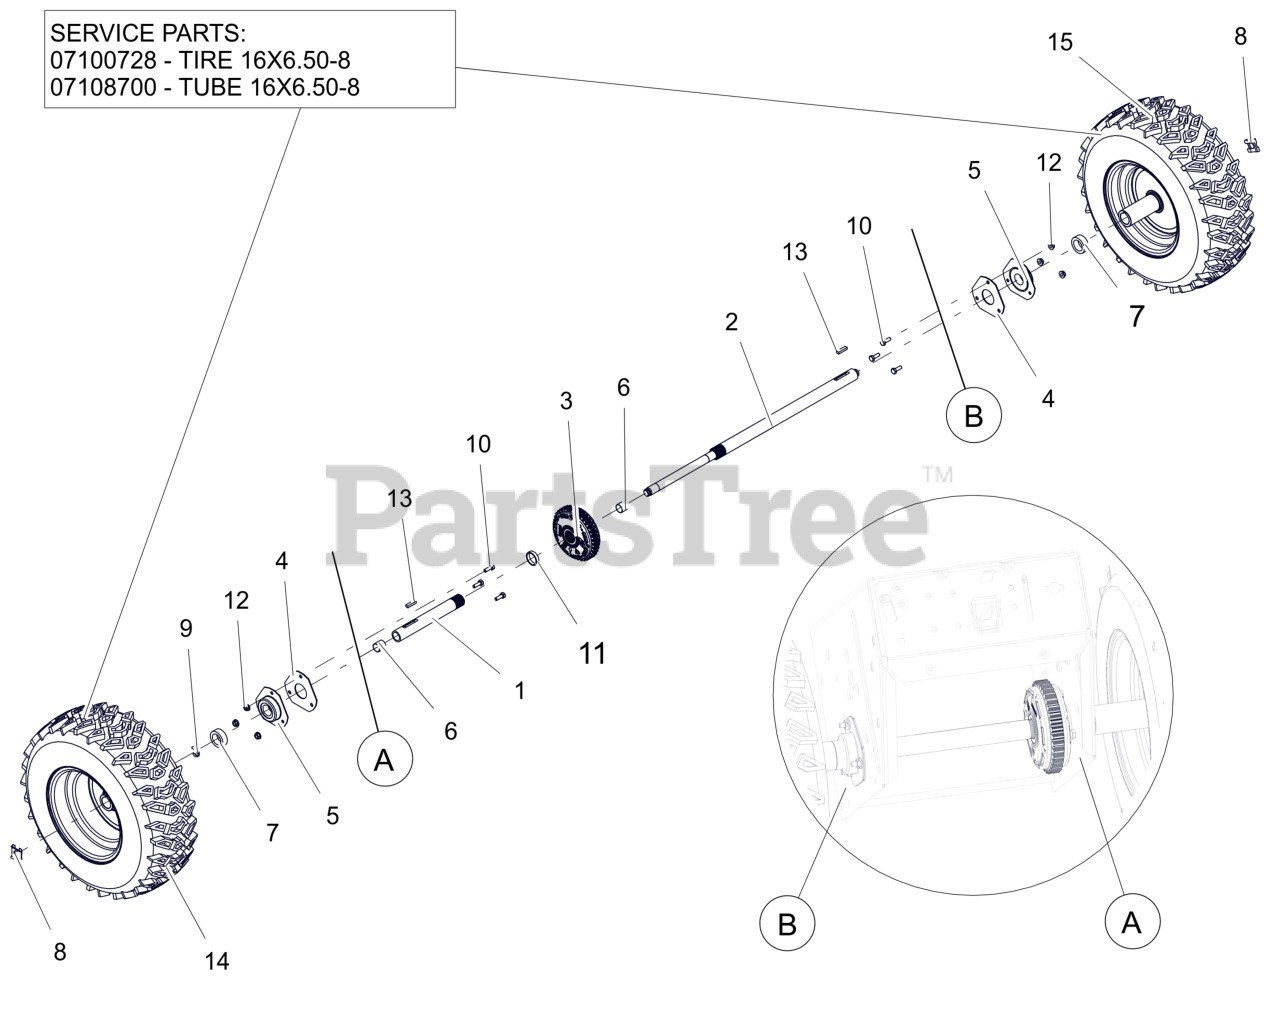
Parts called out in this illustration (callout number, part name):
1	AXLE, SHORT-AUTO W/BUSHINGS
2	AXLE, LONG-PRO AUTO DIFF
3	DIFFERENTIAL, AUTOMATIC
4	PLATE, BEARING SPACER
5	BRG-FLG 1.003/1.000 3 BOLT
6	BSHG-SLV .706X.764X.75 BRZ
7	SPACER, PRO AXLE BEARING
8	CLIP, SNAP .625 DIA
9	RG-RTNG-EXT .625X.042
10	BLT, HEX .25-20X.75 G5 ZCC
11	BSHG, SLV 1.062X1.228X.268
12	NUT-LK-CTR-FLG .25-20 ZC120
13	KEY-RECT .25X.188X1.00
14	TIRE/WHEEL RH 16X6.5-8 DIFF T2
14	TIRE, 16X6.50-8 K478
14	TUBE
15	TIRE/WHEEL LH 16X6.5-8 DIFF T2
15	TIRE, 16X6.50-8 K478
15	TUBE
